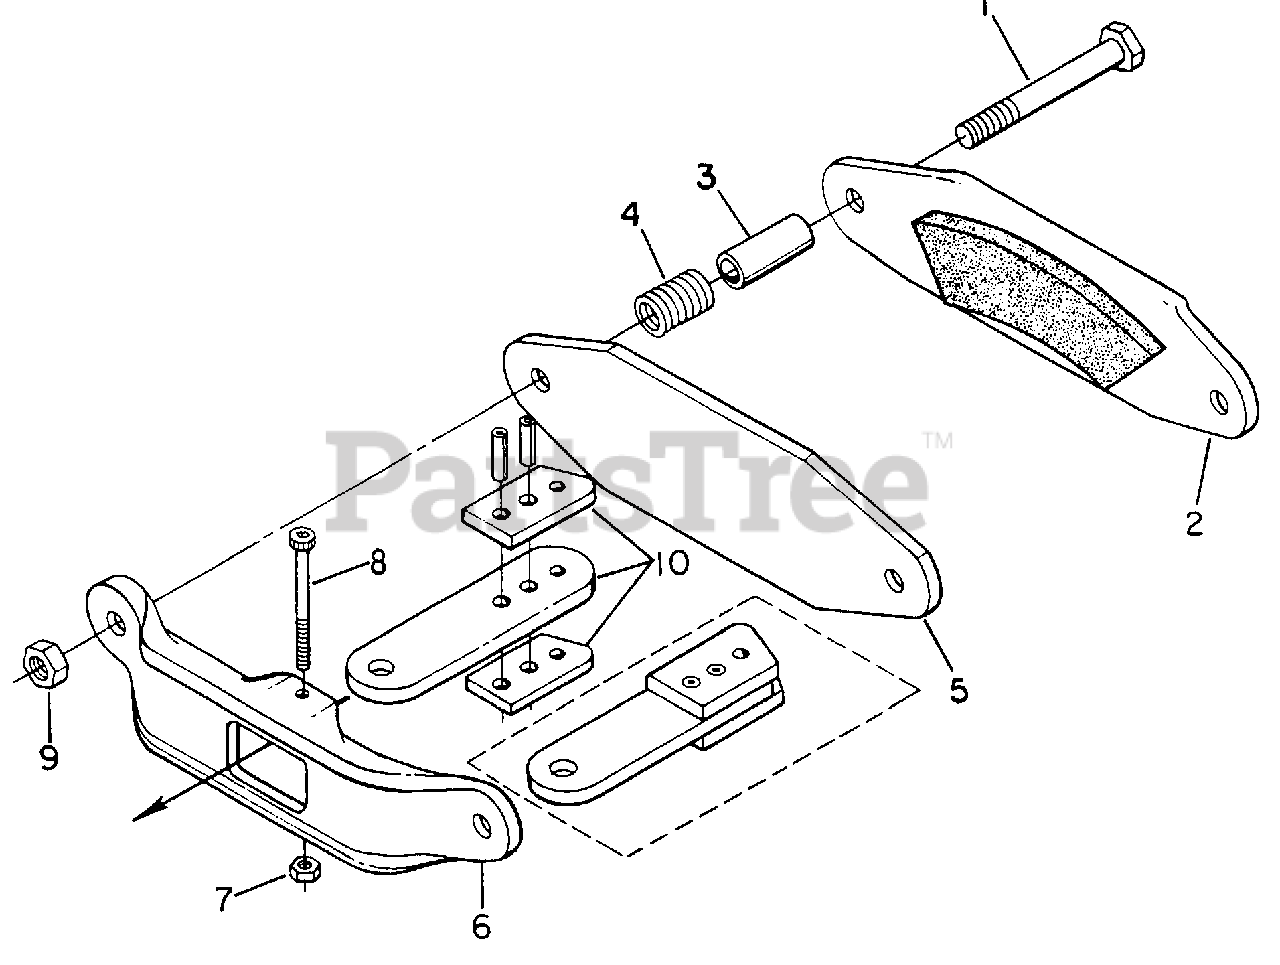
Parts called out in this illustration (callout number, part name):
1	Bolt, 3/8-NF X 2-1/4
2	Pad, Outer
3	Spacer
4	Spring, Compression
5	Pad, Inner
6	Bracket, Actuator
7	Nut, Hex Top Lock Jam, 5/16-18 GR5
8	Screw, Shoulder
9	Nut, Hex Lock, 3/8-24
10	Cam, Actuating
